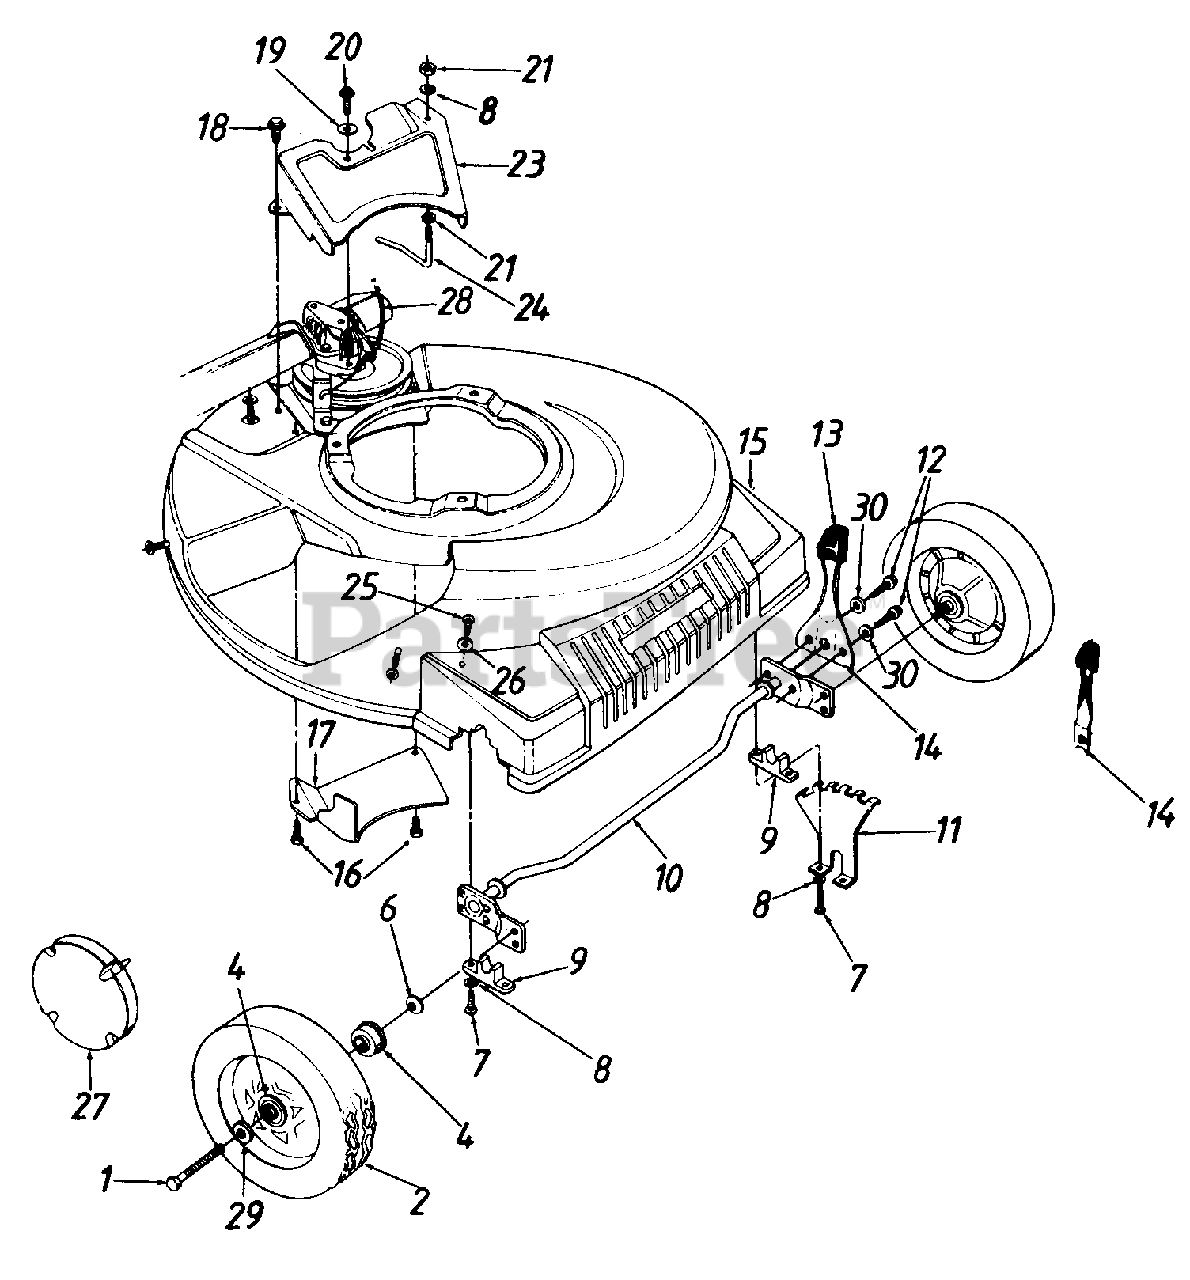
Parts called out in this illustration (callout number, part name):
1	Front Axle Bolt
2	Wheel Ass'y. Comp. 8 x 2"
4	Flange Ball Brg. .501" I.D.
6	Bell-Wash. .380" I.D. x .88
7	Hex Wash. Hd. B-Tap Scr. 1/4-20
8	L-Wash. 1/4" I.D.
9	Block Bushing
10	Axle Ass'y.
12	Hex Wash. Hd. TT-Tap Scr. 1/4-20 x . 5 " Lg.
13	Knob
14	Spring Lever (With 1 hole)
15	Plastic Front End
16	Hex B-Tap Scr. 1/4" x .38"
19	Bell-Wash. .265" I.D. x .75
20	Hex Wash. Hd. B-Tap Scr. 1/4 x .62"
21	Hex Nut 1/4-20 Thd.
25	Truss B-Tap Scr. 5/16 x .75"
26	Bell-Wash. .345" I.D. x .88" O.D.
27	Hub Cap
28	S.P. Cable 50" Lg.
29	Wave Wash. .53" I.D. x .78 O.D.
30	External L-Wash. 1/4" I.D.
